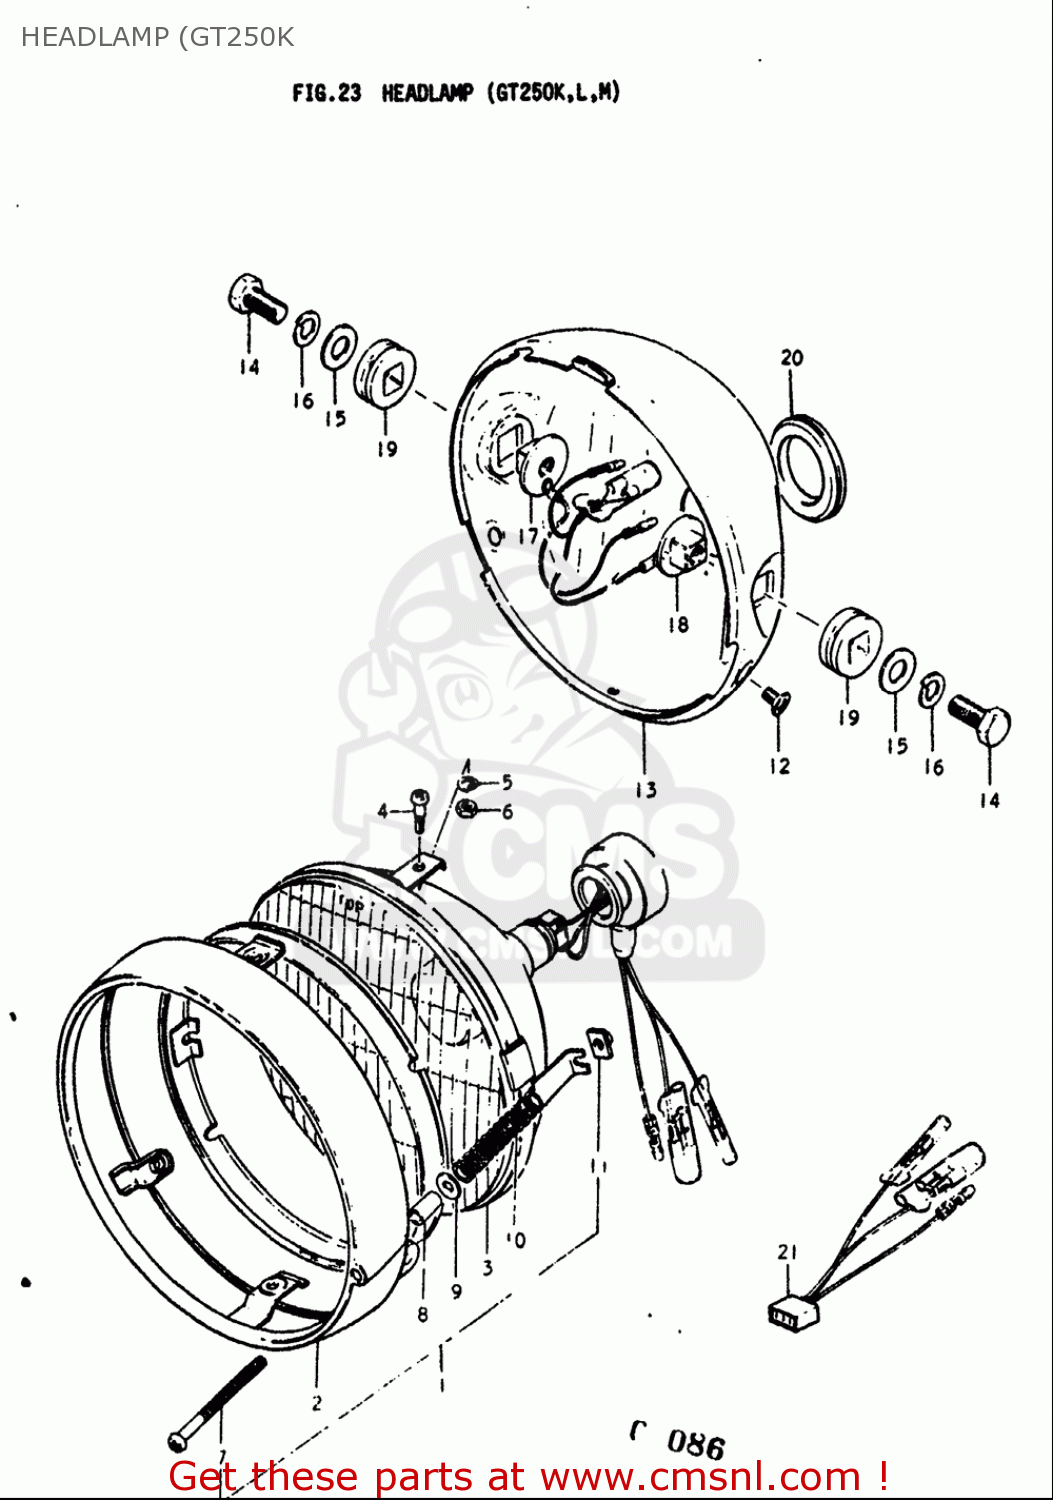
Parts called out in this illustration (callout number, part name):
4	H/LAMP LENS UNIT FITING SCRE
5	WASHER,LOCK
6	NUT
7	SCREW
9	WASHER
11	NUT
12	SCREW
14	BOLT
15	WASHER
16	WASHER,LOCK
19	CUSHION,HEADLAMP HOUSING
20	GROMMET,HEADLAMP HOUSING
21	WIRE,HEADLAMP GROUND
